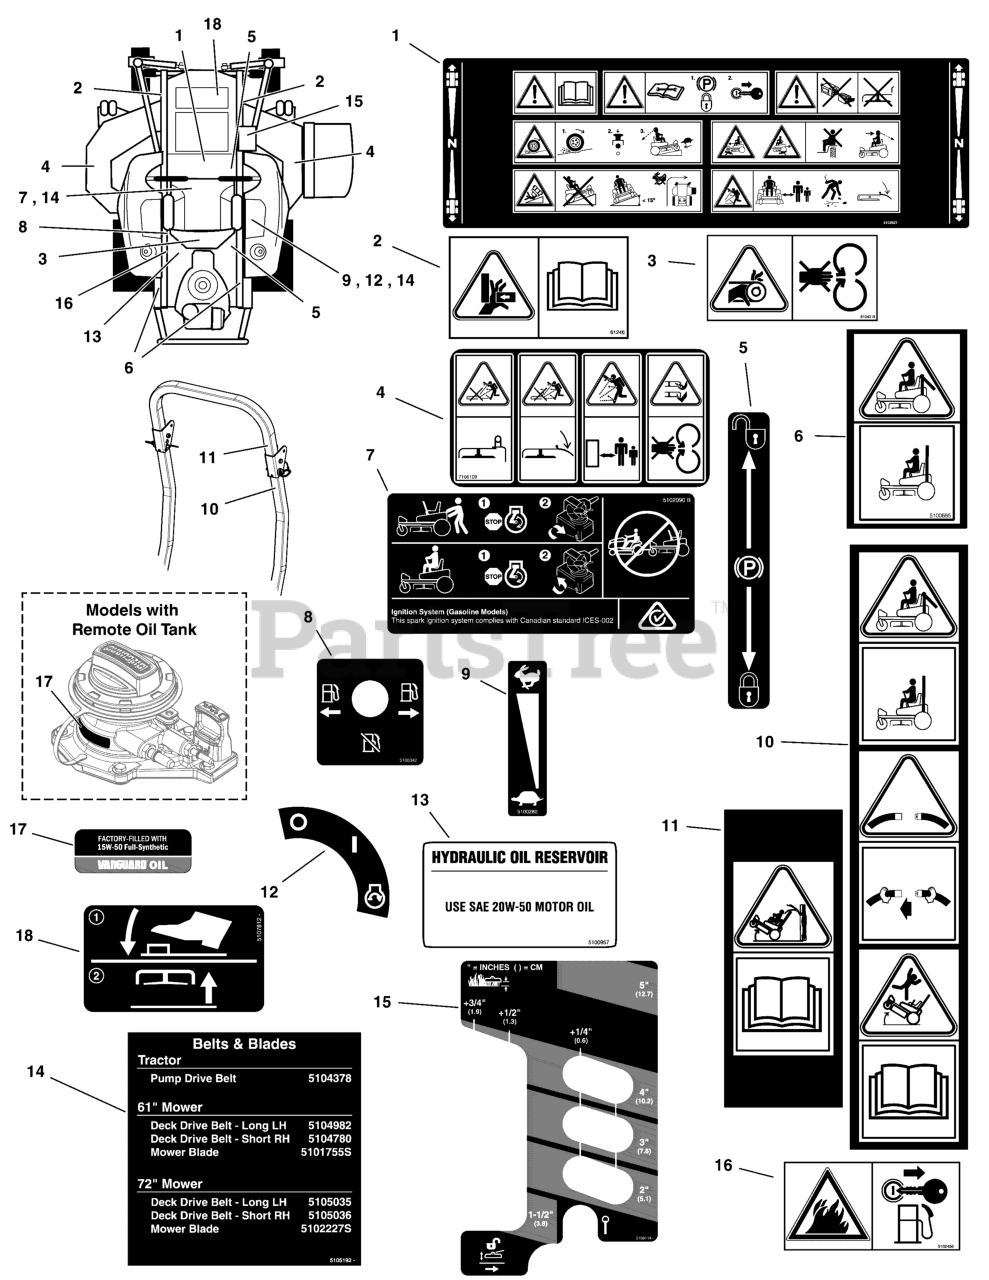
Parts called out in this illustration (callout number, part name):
1	DECAL, MAIN SAFETY, ANSI CE
1	DECAL, MAIN SAFETY, EXPORT
2	DECAL, PINCH POINT, CE
3	DECAL, CE DANGER
4	DECAL, DISCHARGE SAFETY, EXPORT
5	DECAL, PARKING BRAKE SYMBOLS
6	DECAL, WARNING, ROLL BAR, CE
7	DECAL, TRANSAXLE RELEASE, S200XT
8	DECAL, FUEL VALVE
9	DECAL, THROTTLE CONTROL
10	DECAL, SAFETY, CE ROPS (SV)
11	DECAL, SAFETY, CE ROPS, OBS (SV)
12	DECAL, IGNITION SWITCH
13	DECAL, HYDRAULIC OIL, 20W50
14	DECAL, BELT & BLADE IS3200Z 2BELT
15	DECAL, CUT HEIGHT, IS700/ZTS700
16	DECAL, FIRE ANSI EXPORT
17	LABEL, OIL INFORMATION
18	DECAL, FOOT OPERATED DECK LIFT
